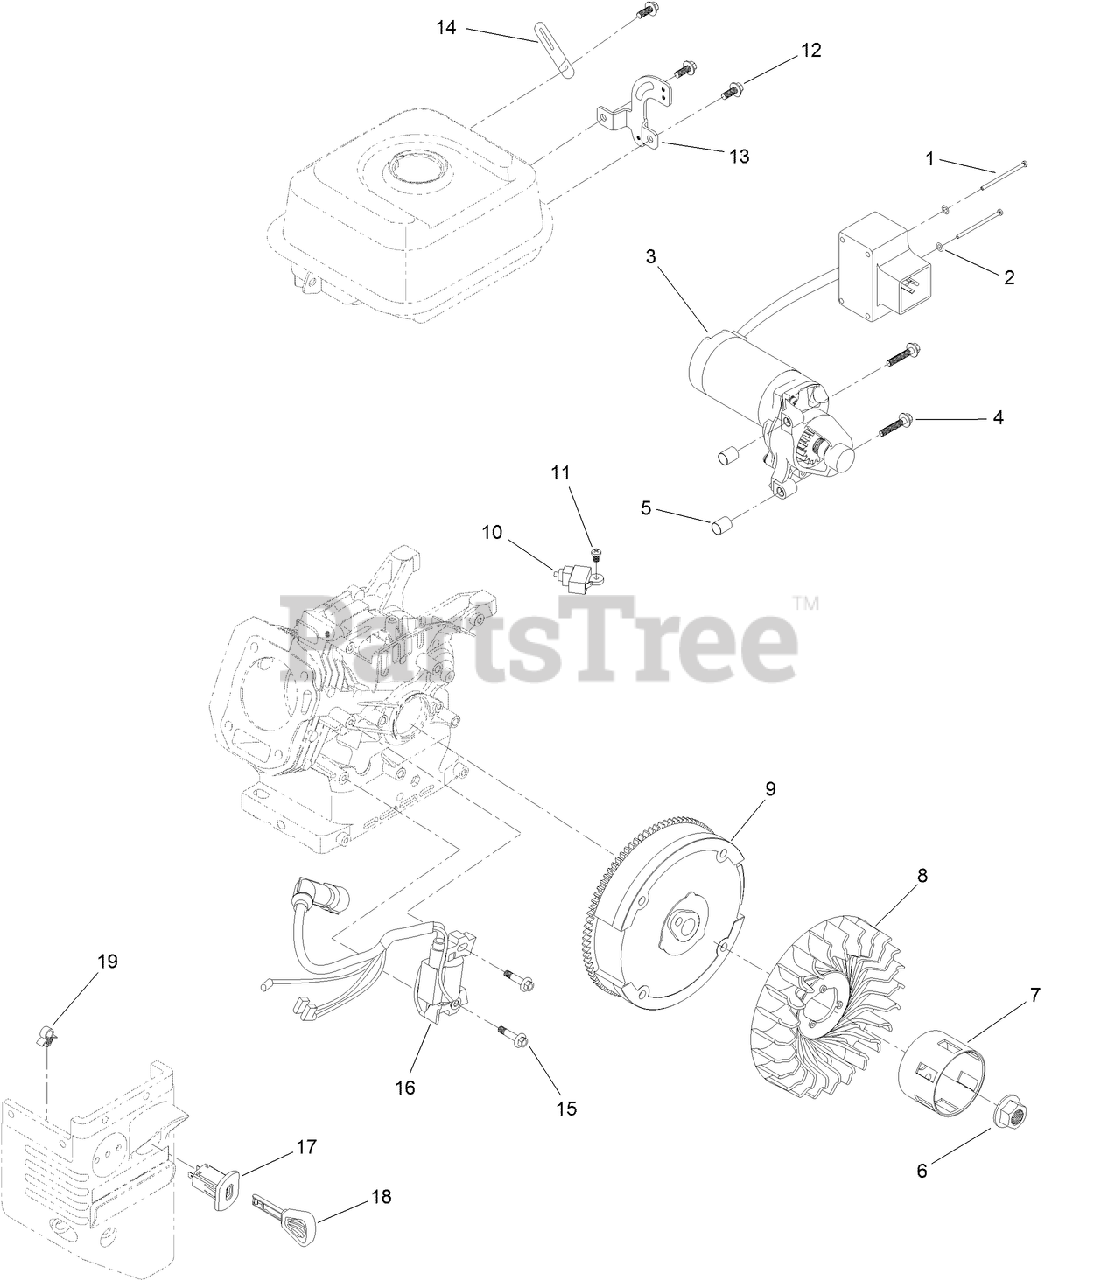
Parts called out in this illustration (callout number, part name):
1	SCREW-BHP
2	WASHER-PLAIN
3	MOTOR-STARTER
4	SCREW-FLANGE
5	PIN-DOWEL
6	NUT-FLANGE
7	CUP-STARTER
10	SWITCH-KILL, ENGINE
11	SCREW-PPH
12	SCREW-HHF
14	CLIP-HARNESS, WIRE
15	SCREW-HHF
16	IGNITION COIL ASM
17	SWITCH-KEY
